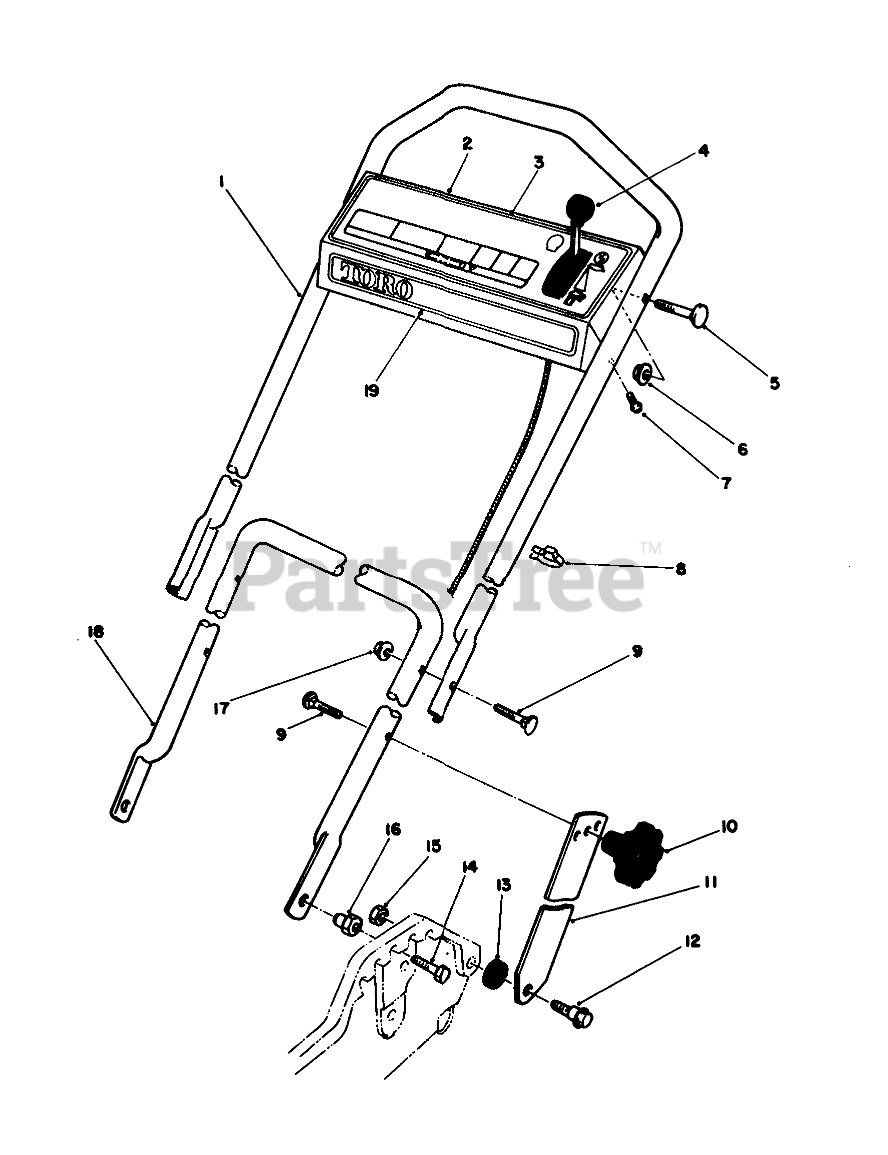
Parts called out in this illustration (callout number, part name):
1	UPPER HANDLE
2	Cover-Control (Incl. Ref. #3)
4	THROTTLE CONT-SERVICE
5	HANDLE SCREW
6	NUT-LOCK, HHF
7	SCREW-HWHTF
9	SCREW
11	Handle Latch
12	SCREW-SHOULDER
13	SPACER
14	SCREW-HH
15	NUT-LOCK, NI
16	HANDLE PIVOT NUT
17	NUT-LOCK, NI
18	LOWER HANDLE
19	Decal-Toro
